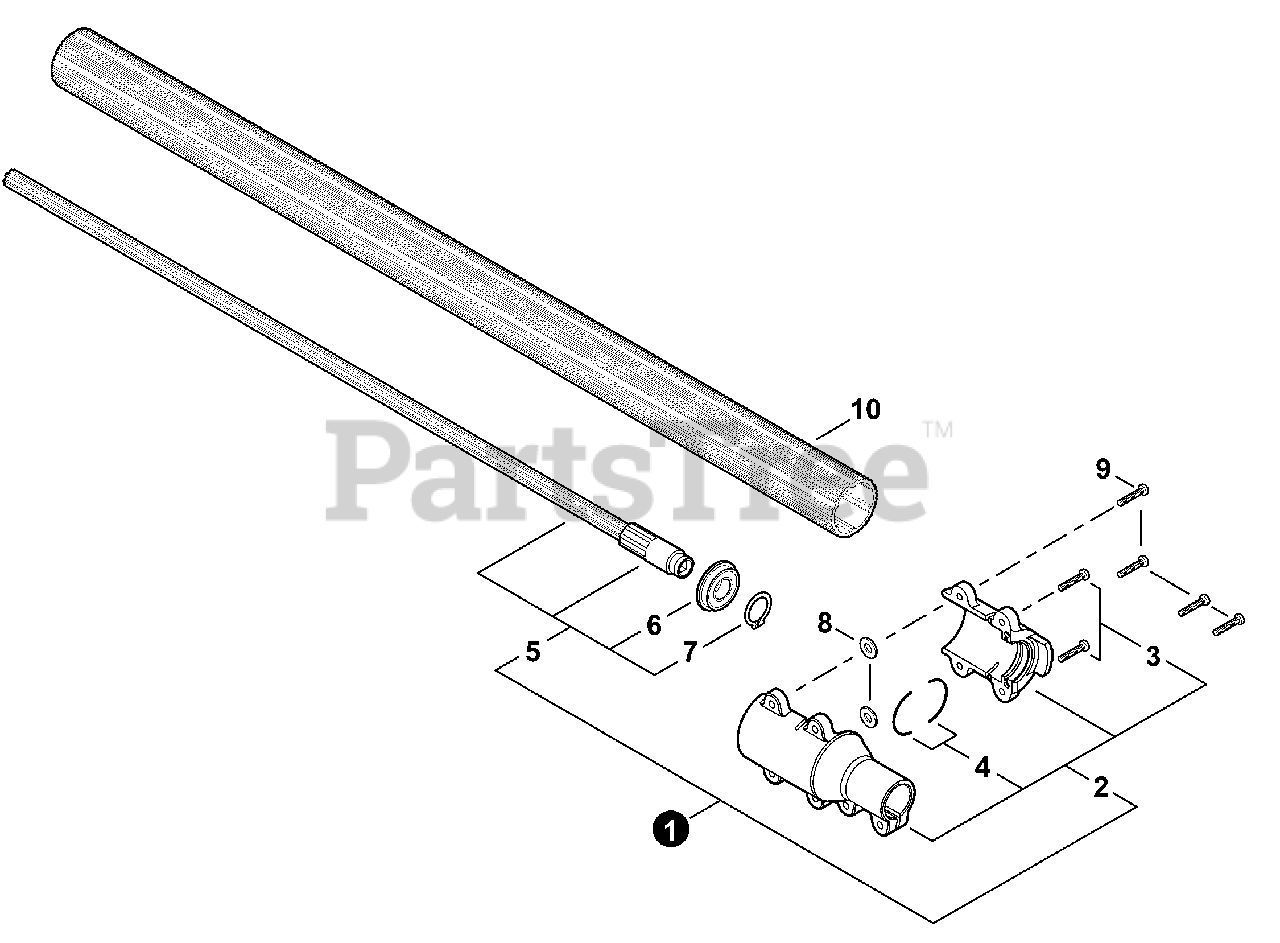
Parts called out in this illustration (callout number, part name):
1	COUPLING/DRIVESHAFT KIT
2	COUPLING ASSY, LOWER
3	BOLT 5×20
4	CUSHION
5	DRIVESHAFT ASSY, LOWER
6	BEARING, BALL 15×32×9
7	RING, RETAINING
8	WASHER 5
9	BOLT 5×20
10	PIPE, MAIN - ORANGE
